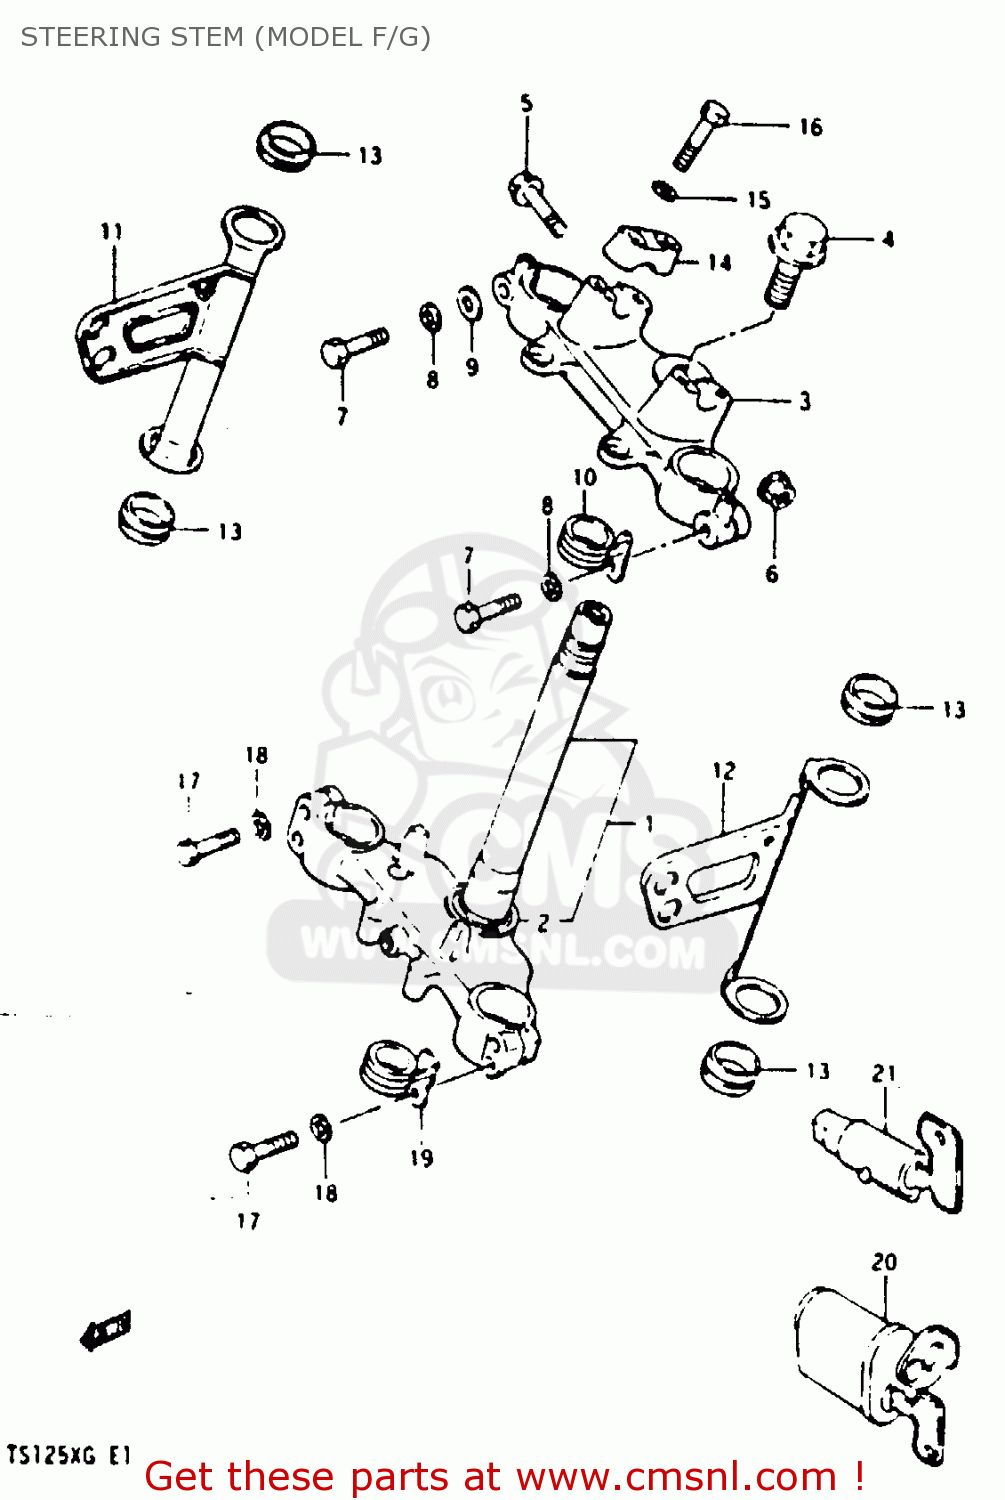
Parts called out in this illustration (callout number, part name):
1	STEM, STEERING (PEARL)
2	BEARING
3	HEAD, STEERING STEM
4	BOLT
5	BOLT
6	NUT
7	BOLT,FORK INNER TUBE FITTING
8	LOCK WASHER
9	WASHER
10	CLIP
11	BRACKET, HEADLAMP RH
12	BRACKET, HEADLAMP LH
13	CUSHION,HEADLAMP HSG BRACKET
14	HOLDER,HANDLEBAR
15	LOCK WASHER
16	BOLT
17	BOLT 8X40
18	LOCK WASHER
19	CLIP
